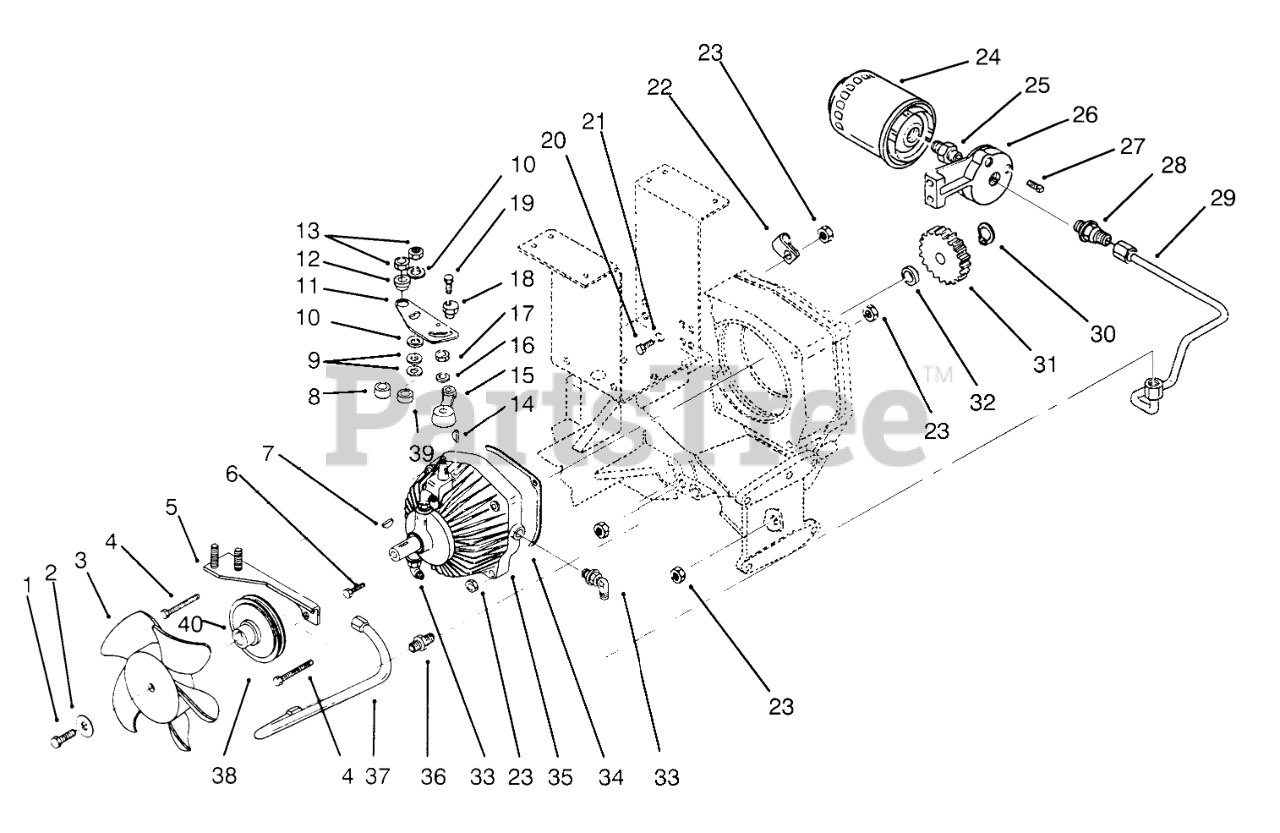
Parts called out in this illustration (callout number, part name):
2	WASHER
3	NYLON FAN-L-CW
4	SCREW-HH
5	ASSY-PLATE B
7	KEY-WOODRUFF
8	SPACER-PIVOT
9	WASHER-SPRING DISC
10	FRICTION WASHER
11	CAM-SPEED CONTROL (NS)
12	CAM-SPACER
14	KEY-WOODRUFF
15	ARM-SPEED CONTROLB
16	WASHER-FLAT
17	NUT-LOCK, NI
19	Screw-HH
20	SCREW-HH
21	WASHER-LOCK
22	CLIP
23	NUT-LOCK, NI
24	OIL FILTER ASM
25	FITTING
26	BASE-FILTER
28	Fitting-Hyd., Straight (Incl. "O"Ring)
29	ASS'Y-TUBE FILTER
30	RING-SNAP, EXTERNAL
31	GEAR 20 TEETH DRIVE
32	SPACER GEAR
33	ELBOW
34	GASKET
35	Pump & Motor
36	FITTING-TUBE
37	ASSY-TUBE SUCTION
38	PULLEY
39	SPACER-FRICTION
